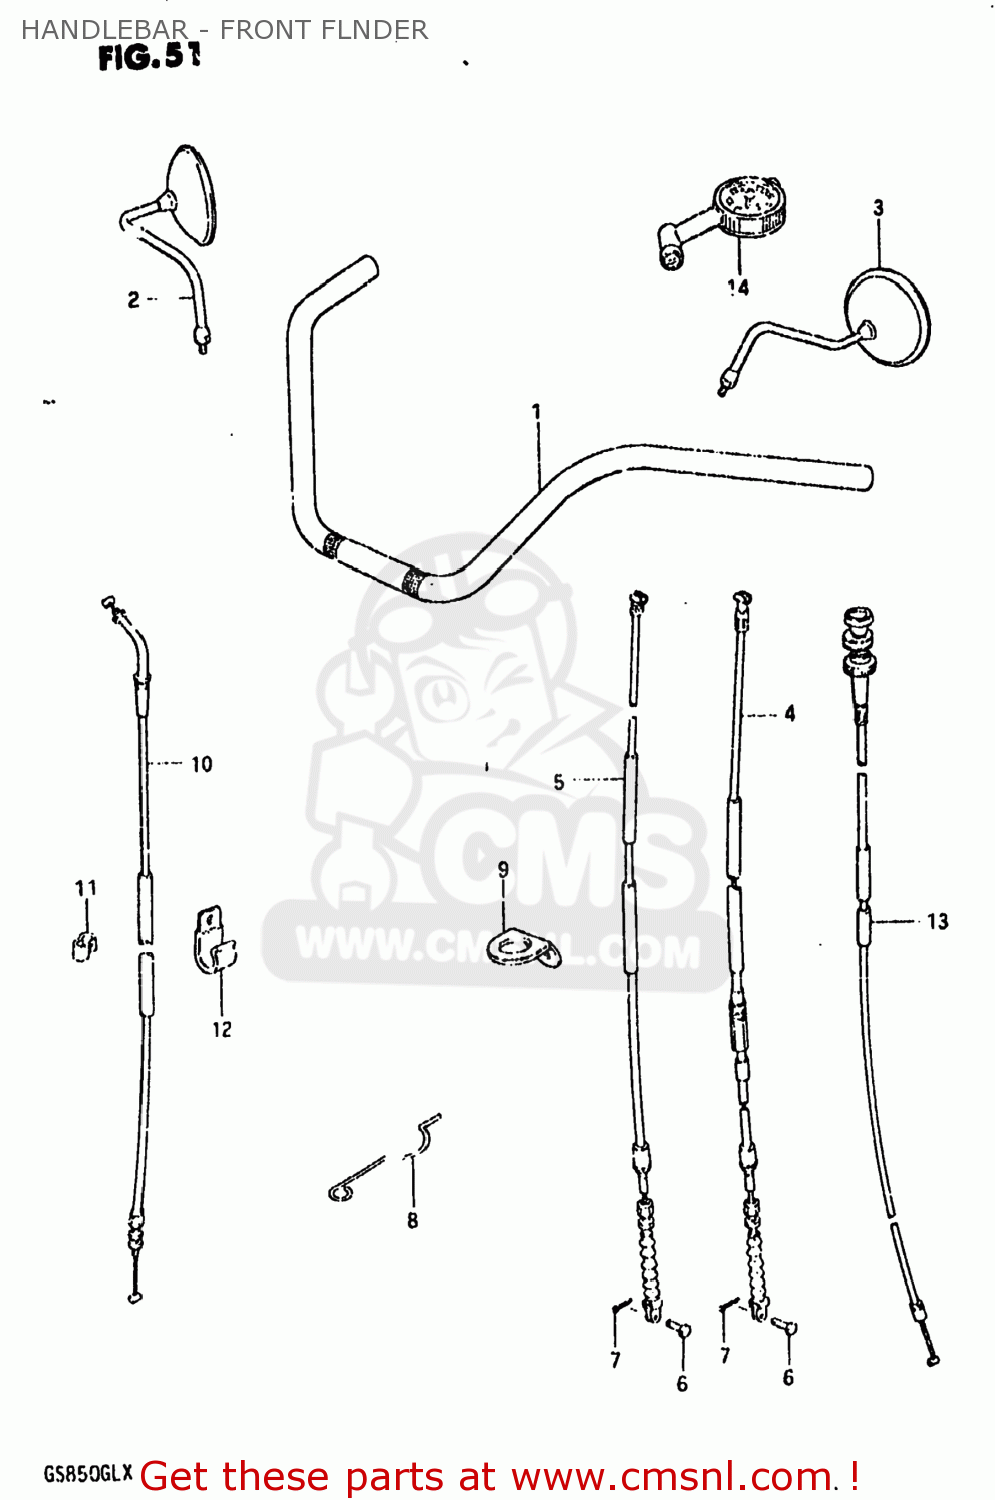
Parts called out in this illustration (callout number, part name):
1	HANDLEBAR
2	MIRROR ASSEMBLY,RIGHT
3	MIRROR ASSEMBLY,LEFT
4	CABLE ASSY,CLUTCH
5	CABLE ASSY,CLUTCH
6	PIN(L:15)
7	PIN
8	GUIDE,CABLE
9	GUIDE,BRAKE HOSE
10	CABLE ASSEMBLY,THROTTLE
11	CLIP
12	CLAMP
13	CABLE ASSEMBLY,STARTER
14	GAUGE ASSY,AIR PRESSURE
